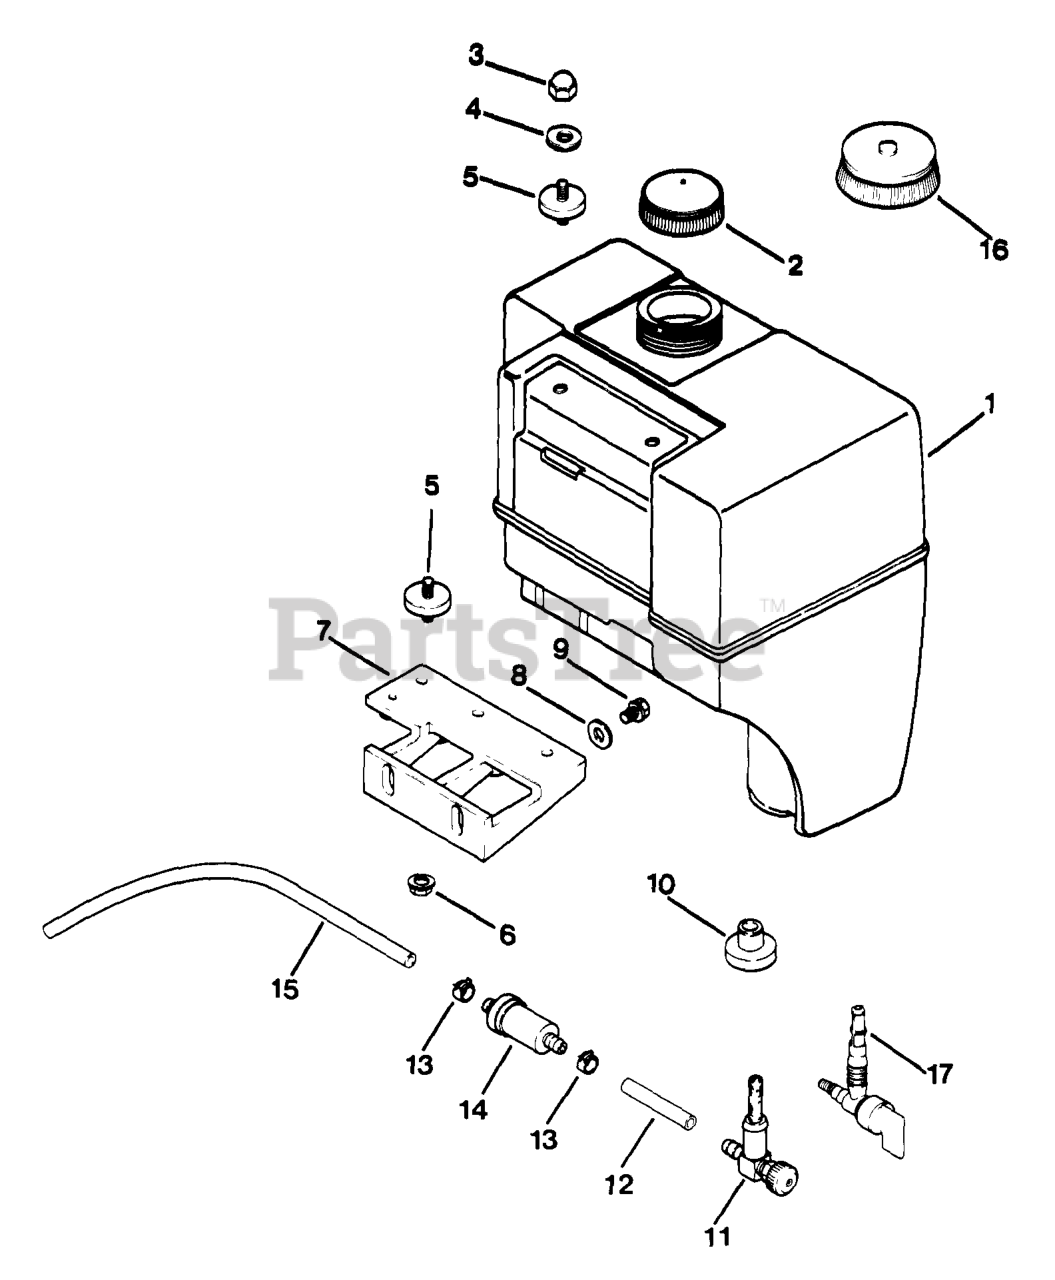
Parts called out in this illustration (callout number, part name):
1	KIT - USE 47 755 39
1	KIT, FUEL TANK
3	NUT - (#DSC)
4	WASHER, PLAIN 1/4"
5	KIT - USE 47 760 01
6	PALNUT, 1/4-20
9	SCREW, SEMS 3/8-16X1-1/4" - DISCONTINUED
10	Bushing, fuel tank
10	BUSHING, FUEL TANK
12	LINE - DISCONTINUED
13	CLAMP, HOSE
14	FILTER - USE 41 050 03
16	CAP
17	VALVE, FUEL SHUT-OFF
